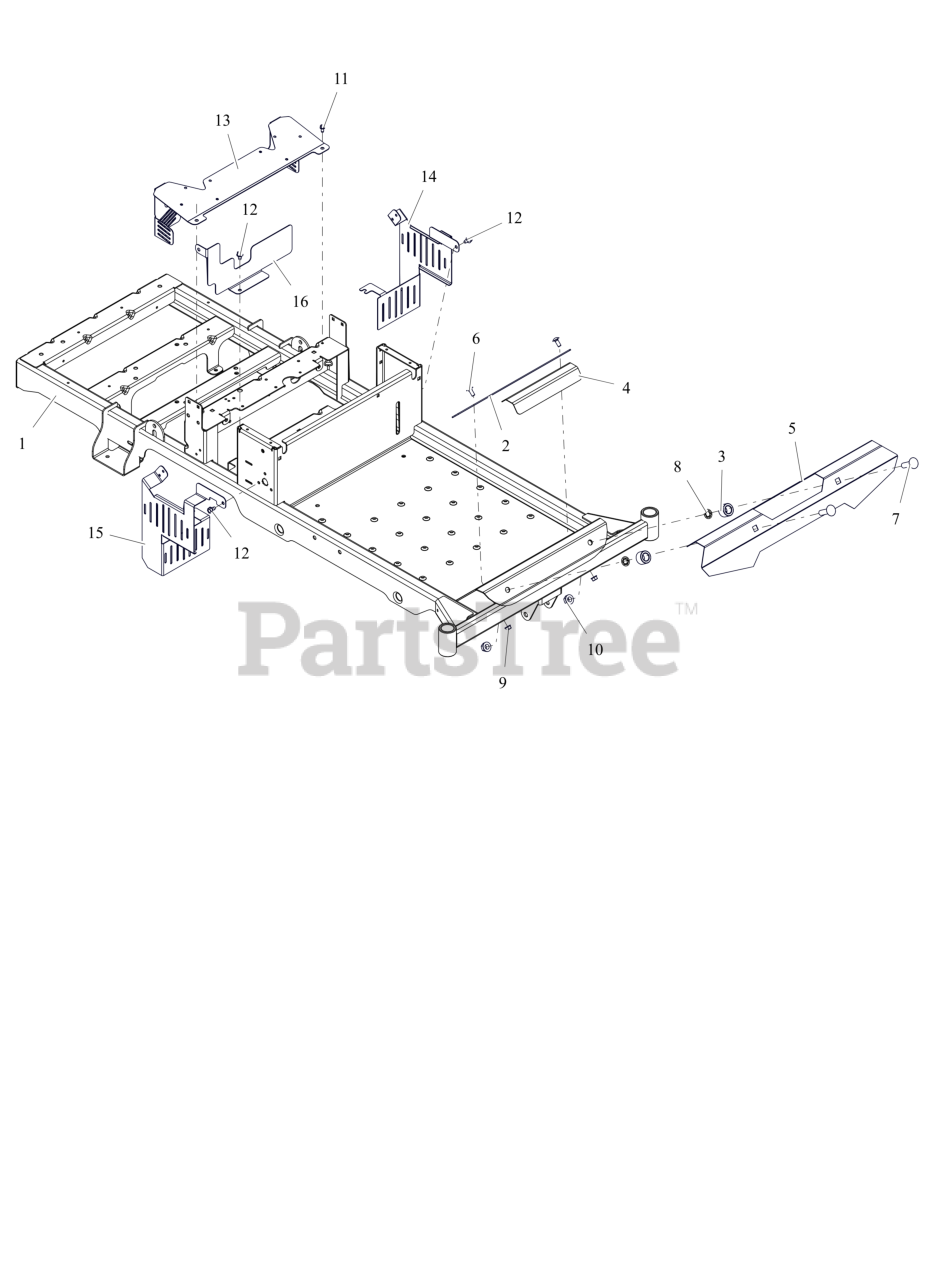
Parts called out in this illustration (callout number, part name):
1	KIT, EDGE FRAME W/DECALS
2	GRIP, ADHESIVE (1" X 16" BLK)
3	TUBE, UPPER CONTROL PIVOT
4	GRIP, STEP
5	FOOTREST, (ORANGE)
6	BLT, RHSSN.31-18X.750 G5 ZCC
7	BLT,RHSN .50-13X1.75 G5 ZCC
8	NUT-PUSH, .50
9	NUT,LK-CTR-FLG .31-18 GF ZCC
10	NUT-LK-CTR-FLG .500-13 GG ZCC
11	SCR-TAP .25-20X.50 HWH ZCC
12	SCR,TAP .312-18X.50 HWH TR ZCC
13	PLATE, FAN GUARD CE (BLACK)
14	SHIELD, LOWER TRANSAXLE LH CE (BLACK)
15	SHIELD, LOWER TRANSAXLE RH CE (BLACK)
16	SHIELD, SEAT TRANSAXLE CE (BLACK)
